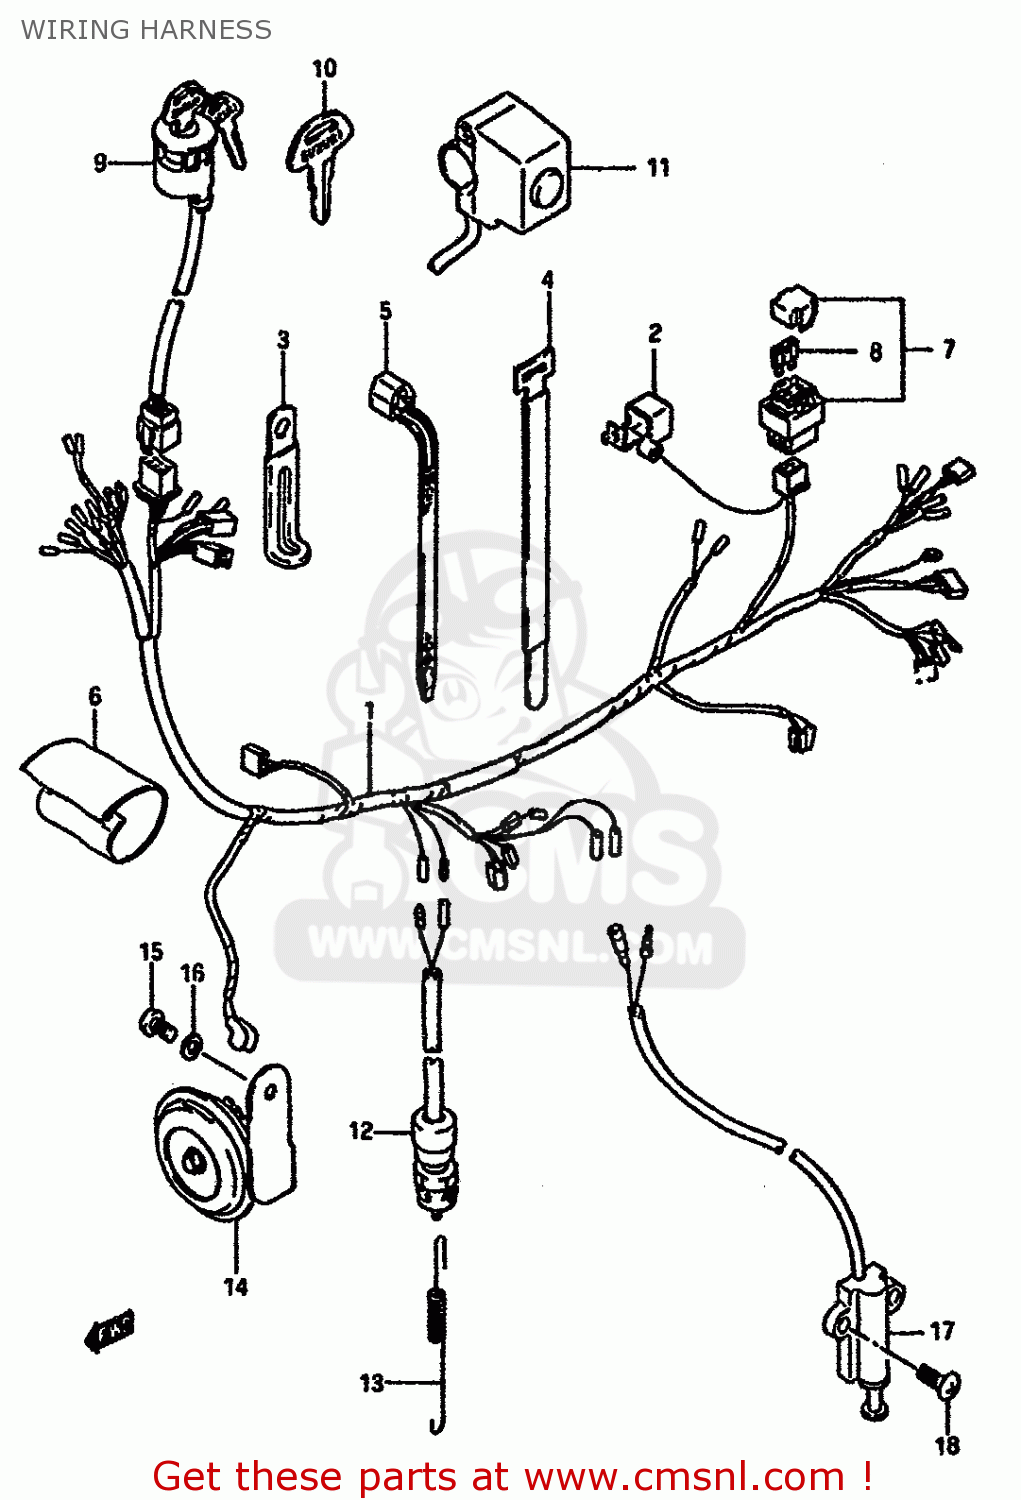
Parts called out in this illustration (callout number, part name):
1	HARNESS, WIRING
2	CAP,BATTERY PLUS TERMINAL
3	CLAMP
4	CLAMP
5	CLAMP(L:165)
6	COVER,WIRING HARNESS
7	BOX ASSY,FUSE
8	FUSE(15A)
9	SWITCH ASSEMBLY,IGNITION
10	KEY,BLANK
11	SWITCH ASSY,ENGINE STOP
12	SWITCH ASSEMBLY,STOP LAMP
13	SPRING
14	HORN ASSY
15	SCREW
16	WASHER,LOCK
17	SWITCH ASSY, SIDE STAND
18	SCREW
